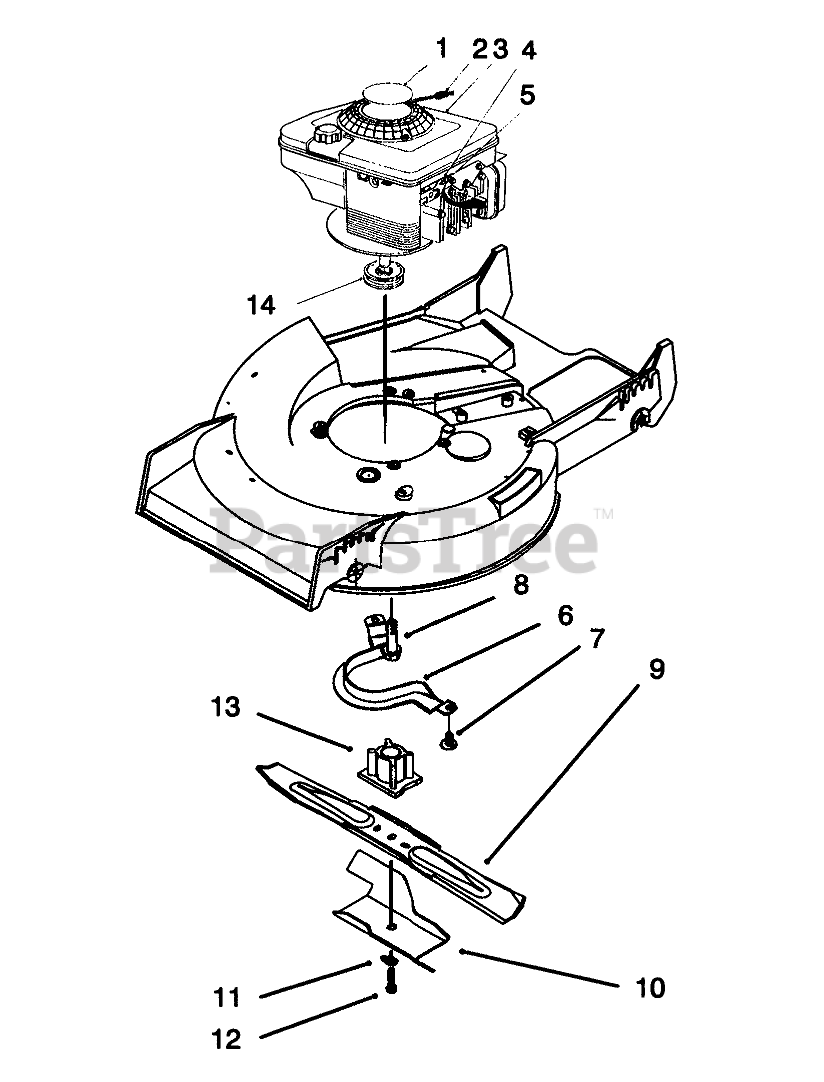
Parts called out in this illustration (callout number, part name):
1	DECAL-ENGINE F/W ENGINE
2	STOP-ROPE
4	CLAMP-CASING
5	Screw
6	Guide-Belt
7	SCREW-HWHTF
8	SCREW-HWH
9	Blade
10	Accelerator
11	WASHER-LOCK
12	SCREW-BLADE
13	BLADE RETAINER
14	PULLEY-DRIVE, ZONE START
